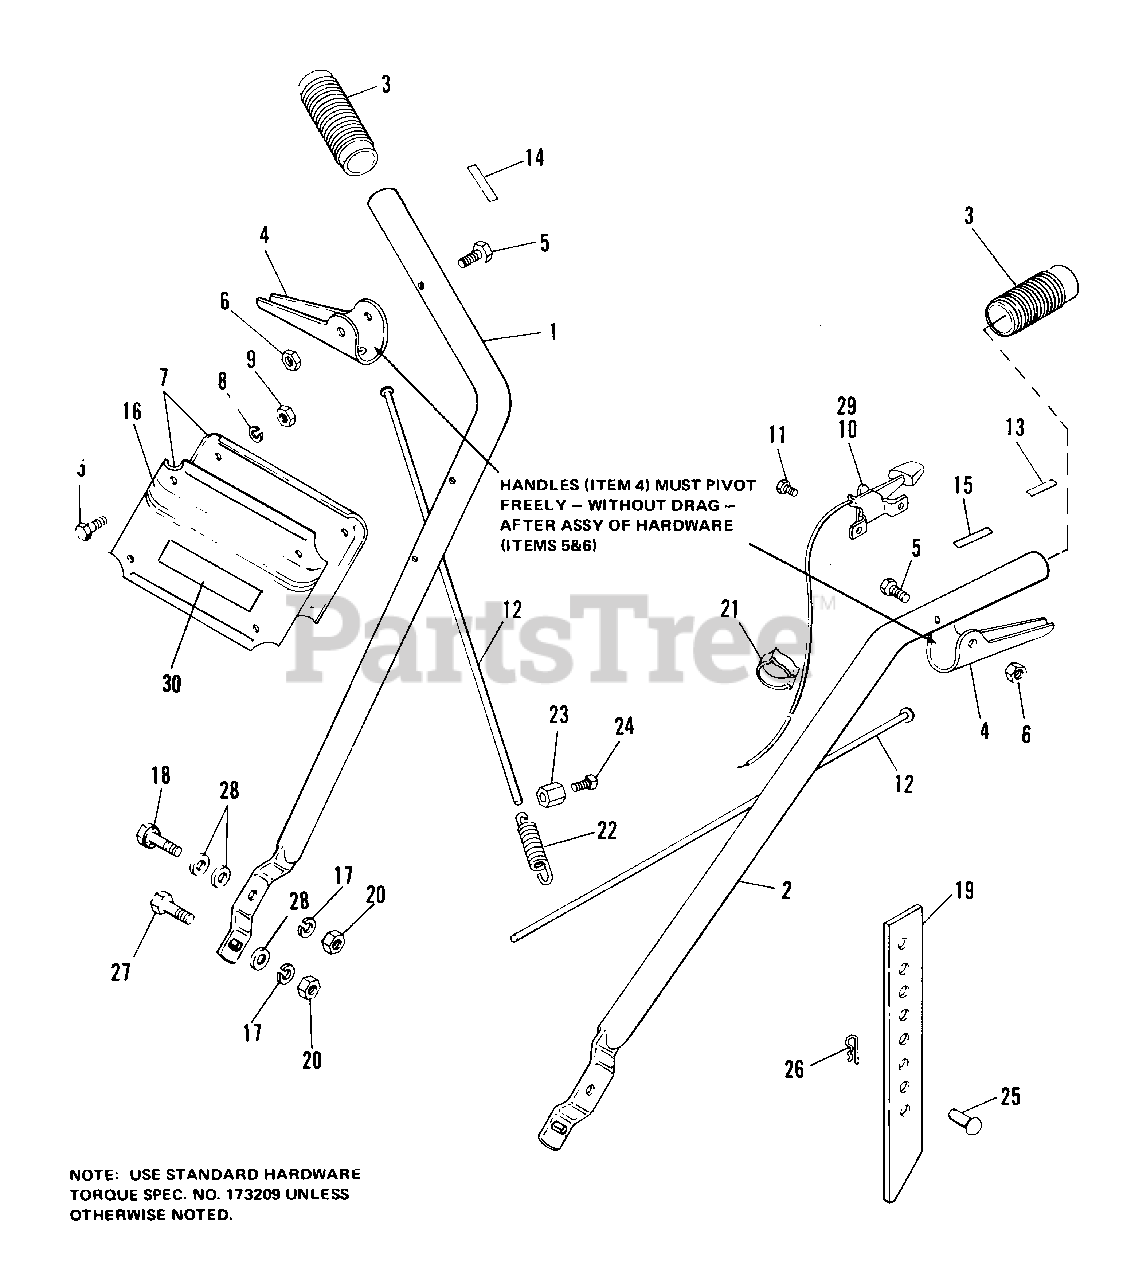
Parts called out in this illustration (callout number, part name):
1	HANDLE, R.H.
2	HANDLE, L.H.
4	* GRIP, Clutch
5	* CAPSCREW, Hex, 1/4-20 x 1-1/2
6	* LOCKNUT, Hex, Full, 1/4-20
7	COVER, Handle
8	LOCKWASHER, 1/4
9	NUT, Hex, Full, 1/4-20
10	CONTROL ASSY, Throttle (1690237)
11	SCREW, Taptite, #10-24 x 1/2
12	* ROD, Control
13	DECAL, Throttle
14	DECAL, Forward
15	DECAL, Reverse (1690324 only)
16	DECAL, Stripe
17	LOCKWASHER, 3/8
18	SCREW, Flange, Whiz, 3/8-16 x 1
19	BAR, Depth
20	NUT, Hex, Full, 3/8-16
21	CLIP, Spring
23	CLAMP, Wire
24	SETSCREW, #10-24 x 5/8
26	PIN, Quick
27	CAPSCREW, Hex, 3/8-16 x 1-1/4
28	WASHER, Plain, 3/8
29	CONTROL, Throttle (1690324 only)
30	FILM, Simplicity
